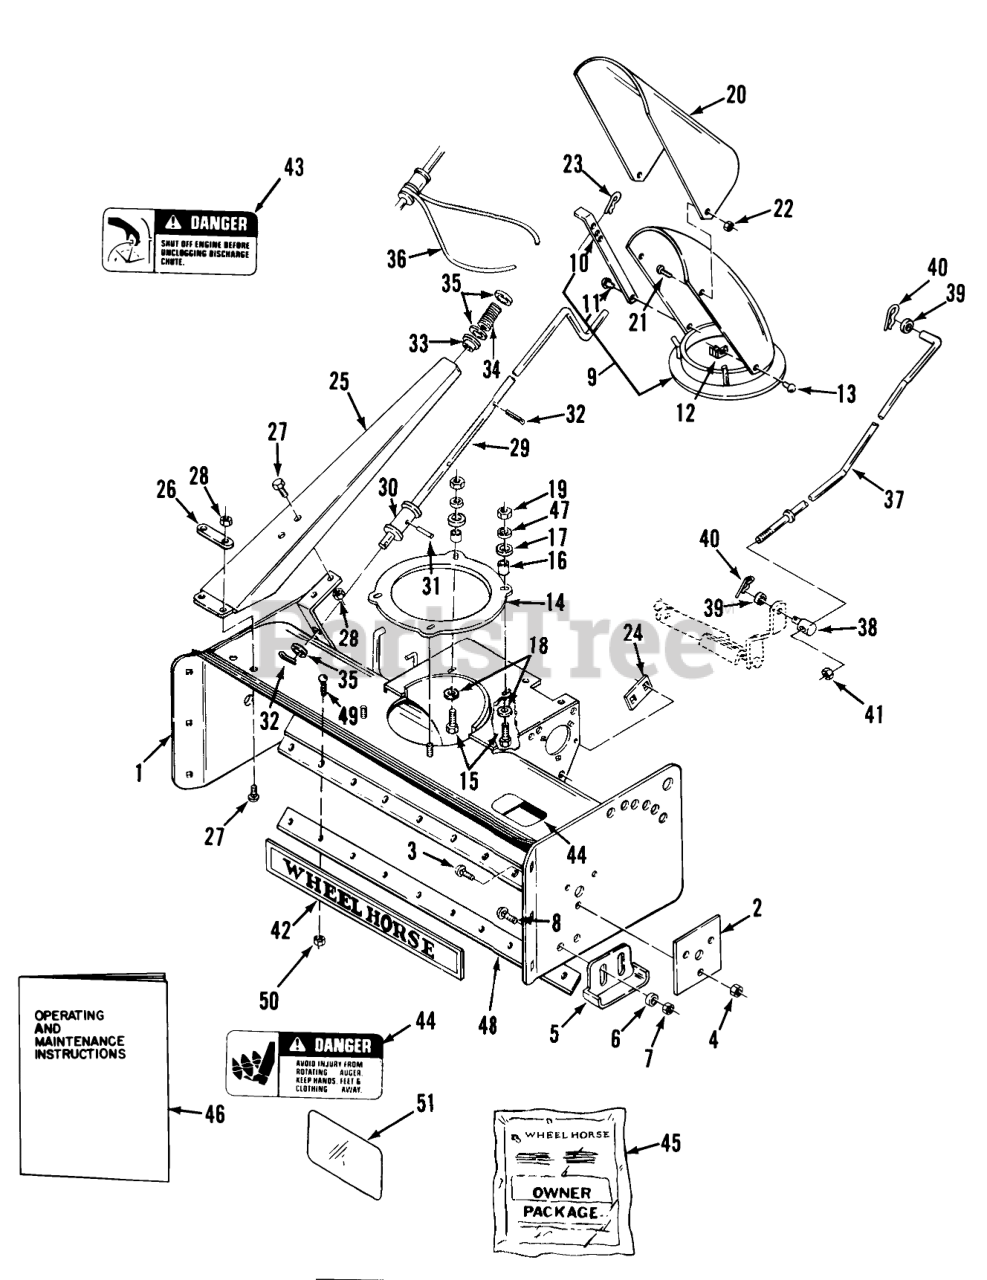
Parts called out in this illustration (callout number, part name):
1	Snowthrower Wrapper Housing
2	Plate
3	Bolt
4	Nut
5	Skid
6	Washer
7	NUT
8	Bolt
9	Shroud (includes items 10 & 11)
10	ARM R
11	RIVET
12	CLAMP
13	RIVET-4
14	COLLAR
15	Bolt
16	SPACER
17	WASHER
18	Washer
19	NUT
20	Deflector
21	MACH. SCREW
22	Nut
23	Hairpin
24	STRAP
25	Crank Support
26	Bar-Reinforcing
27	Bolt
28	NUT
29	CRANK R
30	ASSY TUBE CRANK R
31	ROLL PIN 1/4 X 1-1/4
32	Pop Rivet
33	NYLINER BUSHING
34	SPRING-COMPRESSION
35	Washer
36	CABLE
37	ROD LIFT
38	TRUNION
39	Washer
40	Hairpin Cotter
41	Nut
42	DECAL WHEEL HORSE
43	DECAL DANGER
44	DECAL DANGER
45	Loose Parts Package
46	Owner-s Manual
47	WASHER
48	Reversible Scraper
49	Bolt-Carriage
50	Nut
